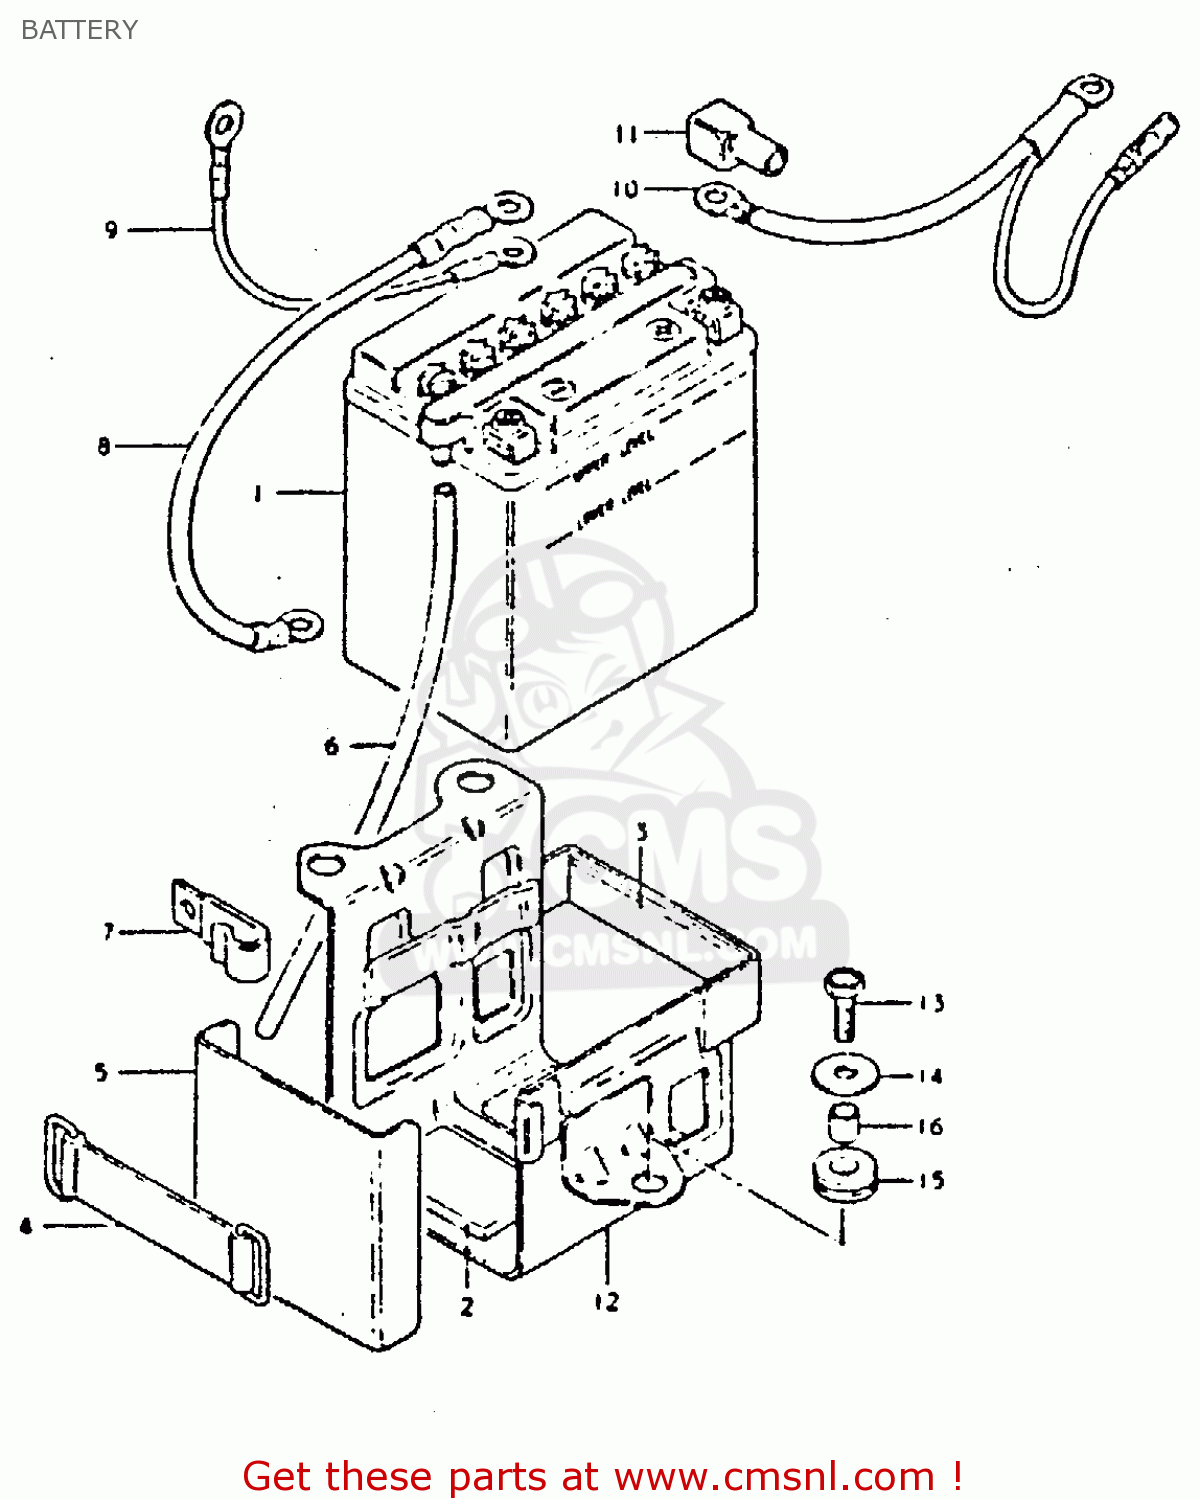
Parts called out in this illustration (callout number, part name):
1	BATTERY ASSY (12V)
2	CUSHION,BATTERY
3	PROTECTOR,20X9
4	BAND
5	COVER,BATTERY
6	HOSE,BATTERY EXHAUST
7	CLAMP
8	CORD,BATTERY MINUS
9	WIRE
10	WIRE,BATTERY PLUS
11	CAP,TERMINAL
12	HOLDER,BATTERY
13	BOLT
14	WASHER
15	CUSHION
16	SPACER (6.1X9X9)
